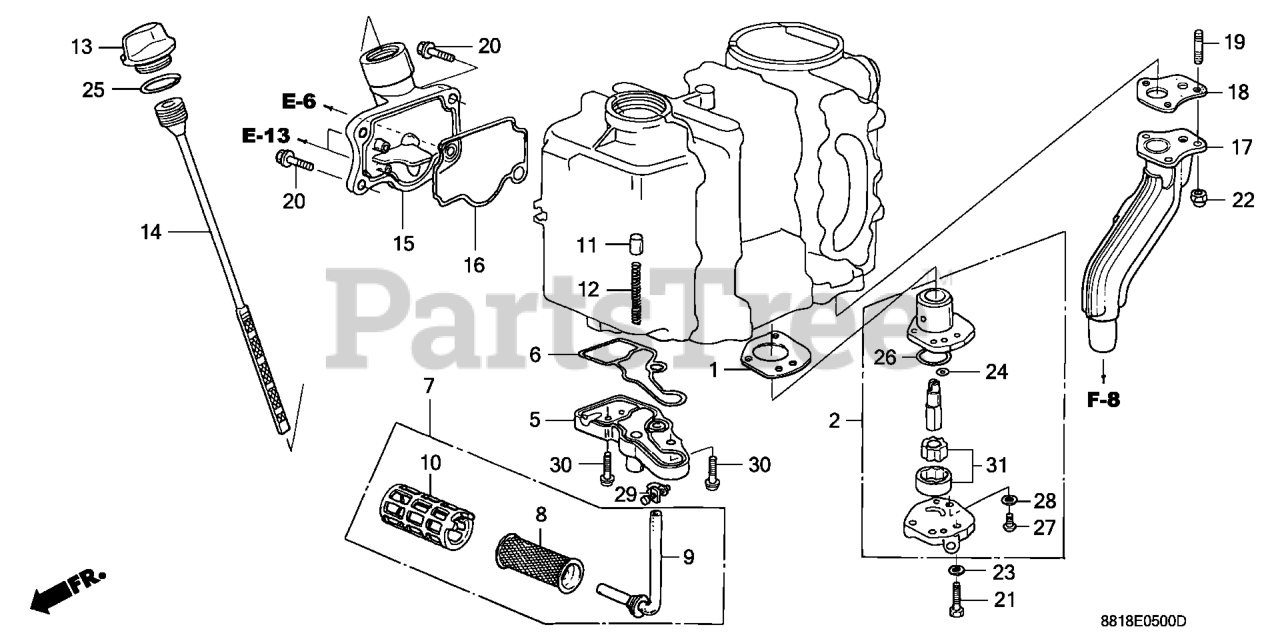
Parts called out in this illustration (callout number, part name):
1	GASKET, PUMP BODY
2	PUMP ASSY., OIL
2	PUMP ASSY., OIL *NH282MU* (OYSTER SILVER METALLIC-U)
3	ROTOR, OIL PUMP (INNER)
4	ROTOR, OIL PUMP (OUTER)
5	FLANGE, OIL FILTER
6	GASKET, OIL FILTER
7	FILTER ASSY., OIL
8	FILTER, OIL
10	HOLDER, OIL FILTER
11	VALVE, CHECK
12	SPRING, VALVE
13	CAP, OIL
14	DIPSTICK, OIL
15	BODY, OIL FILLER
16	GASKET, OIL FILLER BODY
17	PIPE, EX.
18	GASKET, EX. PIPE Use from Engine SN 1204900.
19	BOLT, STUD (6X22)
20	BOLT, FLANGE (6X22)
21	BOLT, FLANGE (6X28)
22	NUT, CAP (6MM)
23	WASHER A (6MM)
24	O-RING (6.8X1.9)
25	O-RING (26X2.7)
26	O-RING (25X1.0)
27	SCREW, PAN (5X10)
28	WASHER, PLAIN (5MM)
29	CLIP, TUBE (10.5MM)
30	BOLT, FLANGE (6X22)
31	ROTOR SET, OIL PUMP
